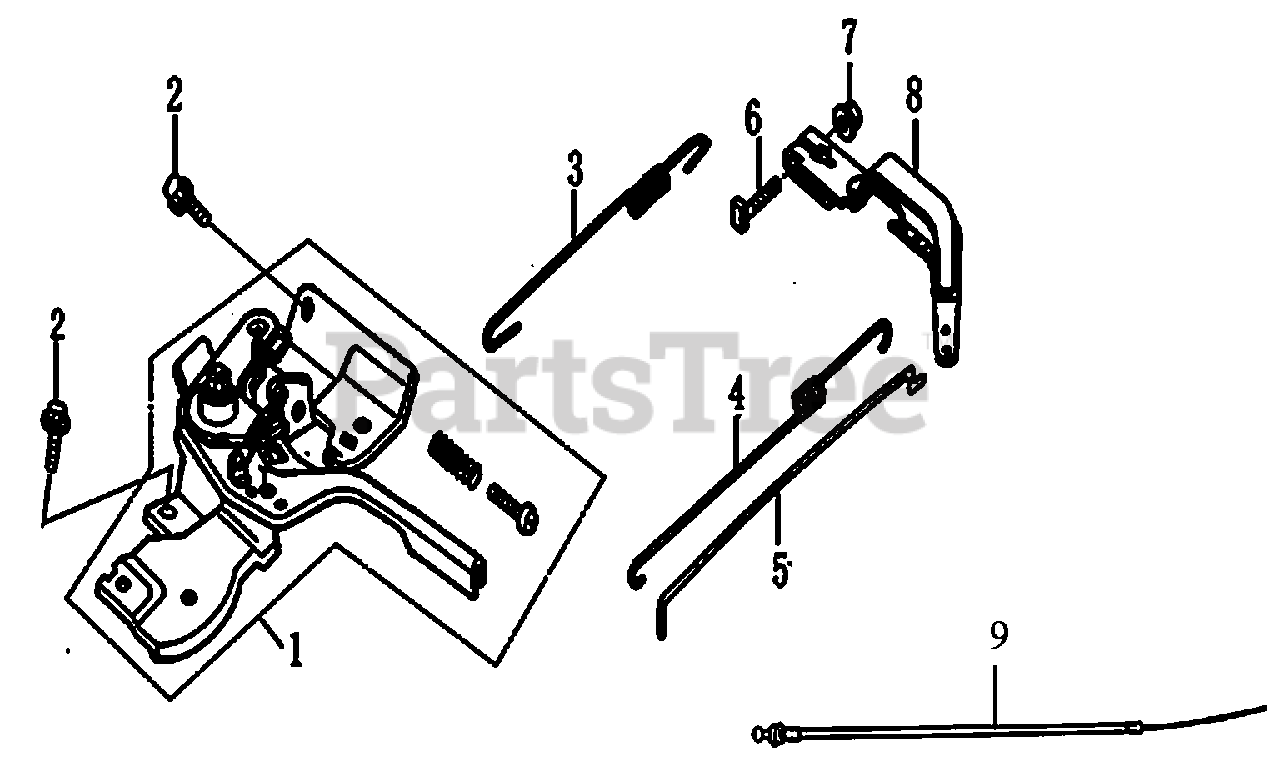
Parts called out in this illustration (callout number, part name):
1	CONTROL ASSY.
2	BOLT, FLANGE
3	SPRING, GOVERNOR
4	SPRING, THROTTLE RETURN
5	ROD, GOVERNOR
6	BOLT, GOVERNOR ARM M6X21
7	NUT, FLANGE
8	ARM, GOVERNOR
9	CABLE, CHOKE
